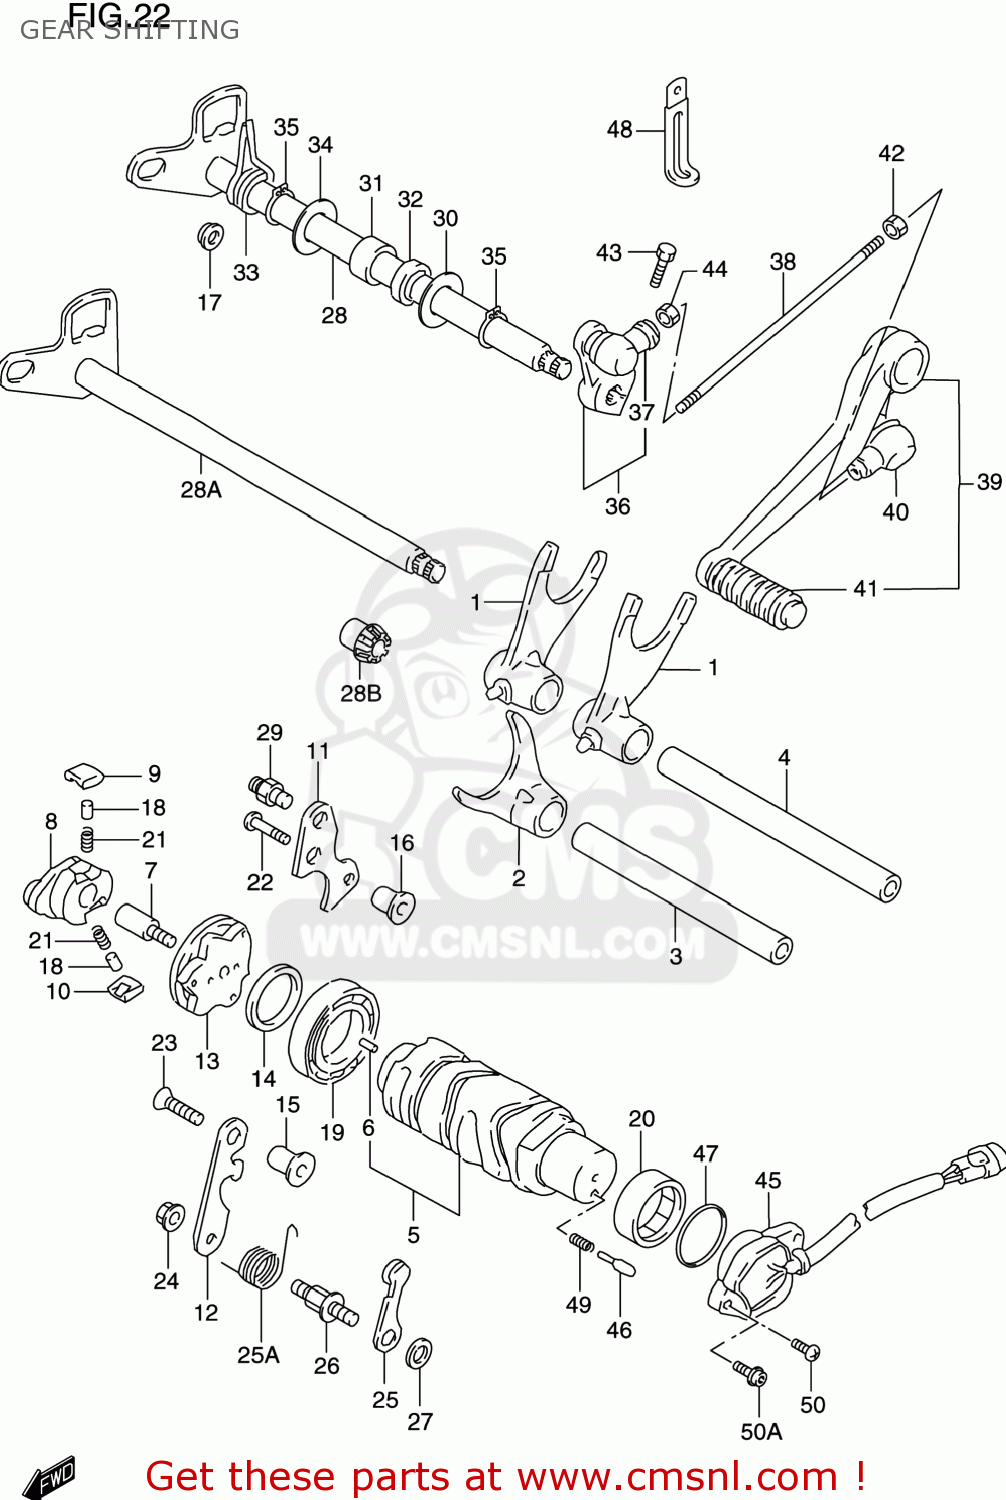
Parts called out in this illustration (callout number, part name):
1	FORK,GEAR SHIFT
2	FORK,GEAR SHIFT NO.3
3	SHAFT,GEAR SHIFT FORK
4	SHAFT,GEAR SHIFT FORK(L:128)
5	CAM,GEAR SHIFT
6	PIN
7	PIN,SHIFT CAM DRIVEN GEAR
8	SHIFTER,GEAR SHIFT CAM
9	PAWL,GEAR SHIFT NO.1
10	PAWL,GEAR SHIFT NO.2
11	LIFTER,GEAR SHIFT PAWL
12	GUIDE,GEAR SHIFT CAM
13	PLATE,GEAR SHIFT CAM
14	WASHER(25X32X3)
15	SPACER(6.1X10X16)
16	SPACER(6.1X10X16)
17	SPACER(7X10X5)
18	PIN(5X8)
19	BEARING(25X47X8)
20	BEARING(25X32X12)
21	SPRING
22	SCREW 6X30
23	SCREW
24	NUT
25	STOPPER,GEAR SHIFT CAM
25A	SPRING,SHIFT CAM STOPPER
26	SUPPORT,CAM STOPPER ARM
27	WASHER
28	SHAFT,GEAR SHIFT
28A	SHAFT,GEAR SHIFT
28B	BUSH,GEAR SHIFT SHAFT
29	STOPPER,GEAR SHIFT CAM
30	WASHER(14X29X0.8)
31	BEARING(14X20X12)
32	SEAL,OIL(14X22X6)
33	SPRING
34	WASHER
35	CIRCLIP
36	ARM,GEAR SHIFT LINK
37	COVER,DUST
38	ROD,GEAR SHIFT LINK(L:165)
39	LEVER ASSY,GEAR SHIFT
40	COVER,DUST
41	RUBBER,GEAR SHIFT PEDAL
42	NUT
43	BOLT
44	NUT
45	BASE ASSEMBLY,GEAR SHIFT TERMINAL
46	PIN(5X15.5)
47	O RING(D:2.4,ID:25.7)
48	CLAMP(L:45)
49	SPRING
50	SCREW
50A	BOLT
